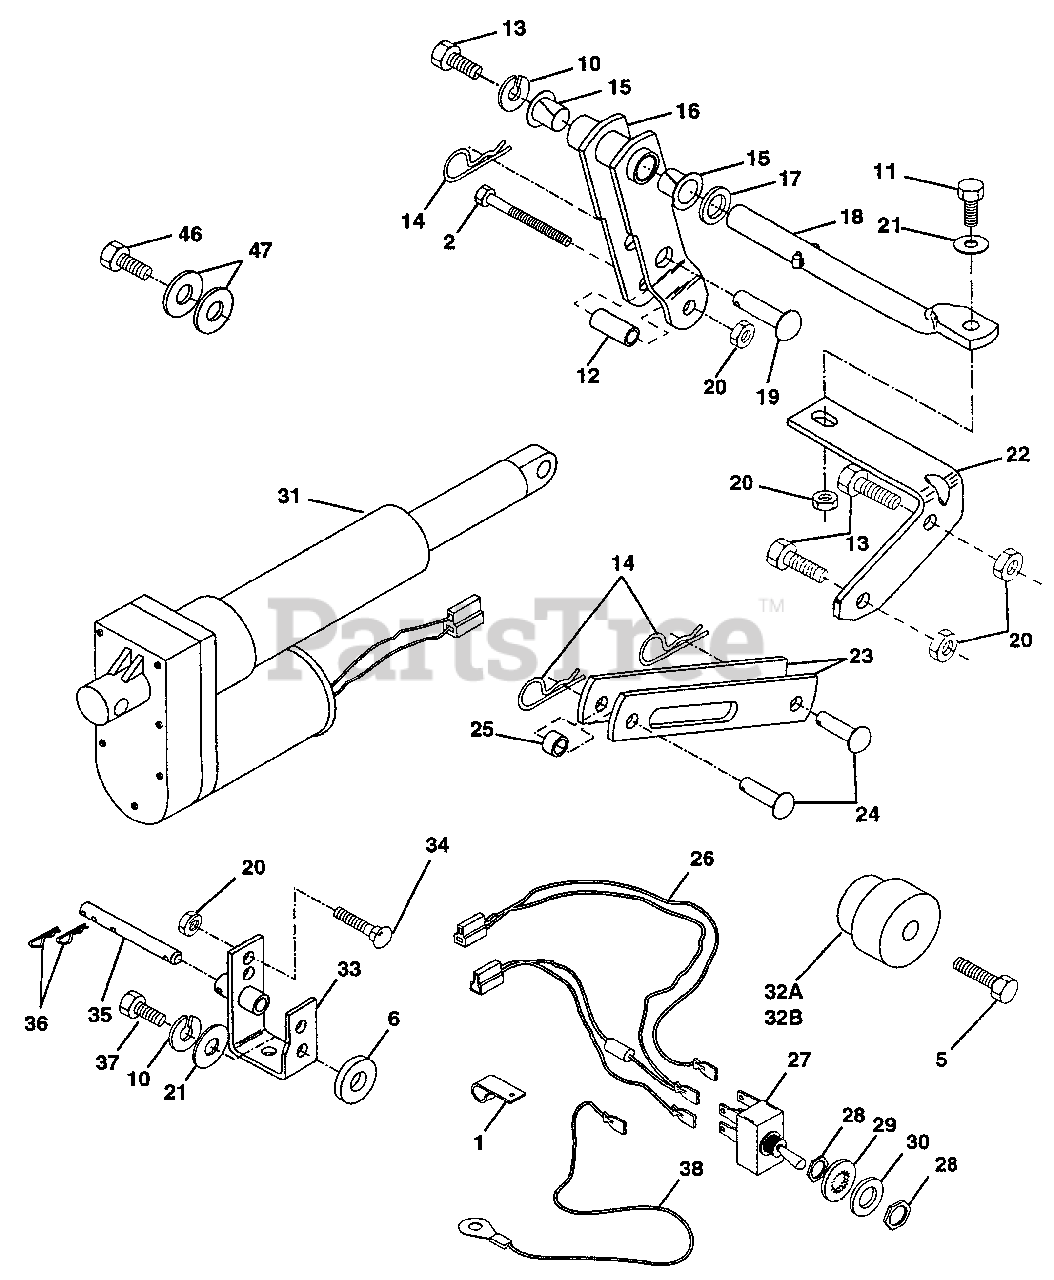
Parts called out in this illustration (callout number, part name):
1	Clip, Insulated
2	Bolt, Hex 3/8-16 x 2-1/4 Grade 5
5	Bolt, Hex 3/8-16 x 1-3/8
6	Washer 13/32 x 7/8 x 7 Ga.
10	Washer, Lock
11	Bolt, Hex 3/8-16 x 1-1 /4
12	Bushing .384 x 1/2 x 1-1/4
13	Bolt, Hex 3/8-16 x 7/8
14	Spring, Retainer
16	Arm, Pivot
17	Washer 21/32 x 1 x 21 Ga.
18	Rod, Pivot Support
19	Pin, Pivot
20	Locknut 3/8-16
21	Washer 13/32 x 7/8 x 16 Ga.
22	Bracket, Pivot Rod
23	Link, Lift
24	Pin, Pivot
25	Spacer
26	Harness, Lift Kit
27	Switch, Lift
28	Nut, Switch
29	Washer, Lock Int. Tooth
30	Washer 15/32 x 3/4 x 16 Ga.
31	Electric, Actuator
32A	Hub, Lever Lift (Splined)
32B	Hub, Lever Lift (Tapered)
33	Bracket, Assembly Actuator, Gear Drive
34	Bolt, Carriage 3/8-16 x 1
35	Pin, Actuator
36	Spring, Retainer
37	Bolt, Hex 3/8-16 x 1
38	Wire, Ground
46	Bolt, Hex 5/16-18 x 1-1/4
47	Washer 11/32 x 1-1/2 x 10 Ga.
